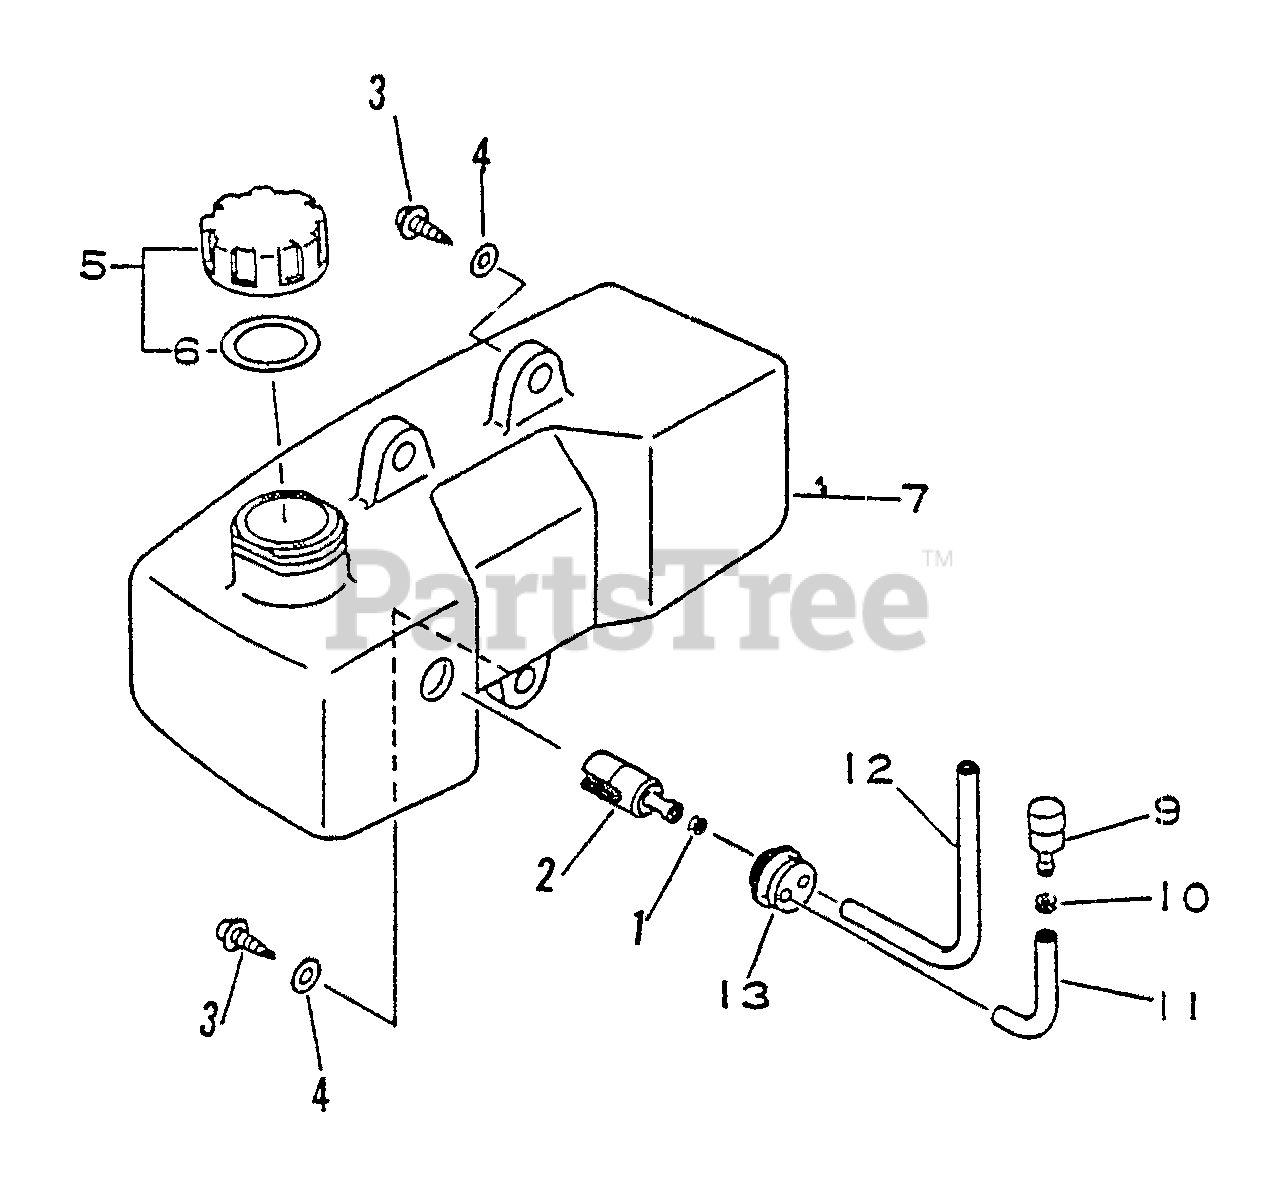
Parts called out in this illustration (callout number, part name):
1	CLIP - 6
2	FILTER, FUEL
3	SCREW - 5X14
4	WASHER - 5
5	CAP ASSY
6	GASKET, CAP
7	TANK, FUEL
9	VENT, FUEL TANK
10	RETAINER, PIPE
11	PIPE - 3X5X70 -- BLACK
12	PIPE - 3X5X210 -- BLACK
13	GROMMET
